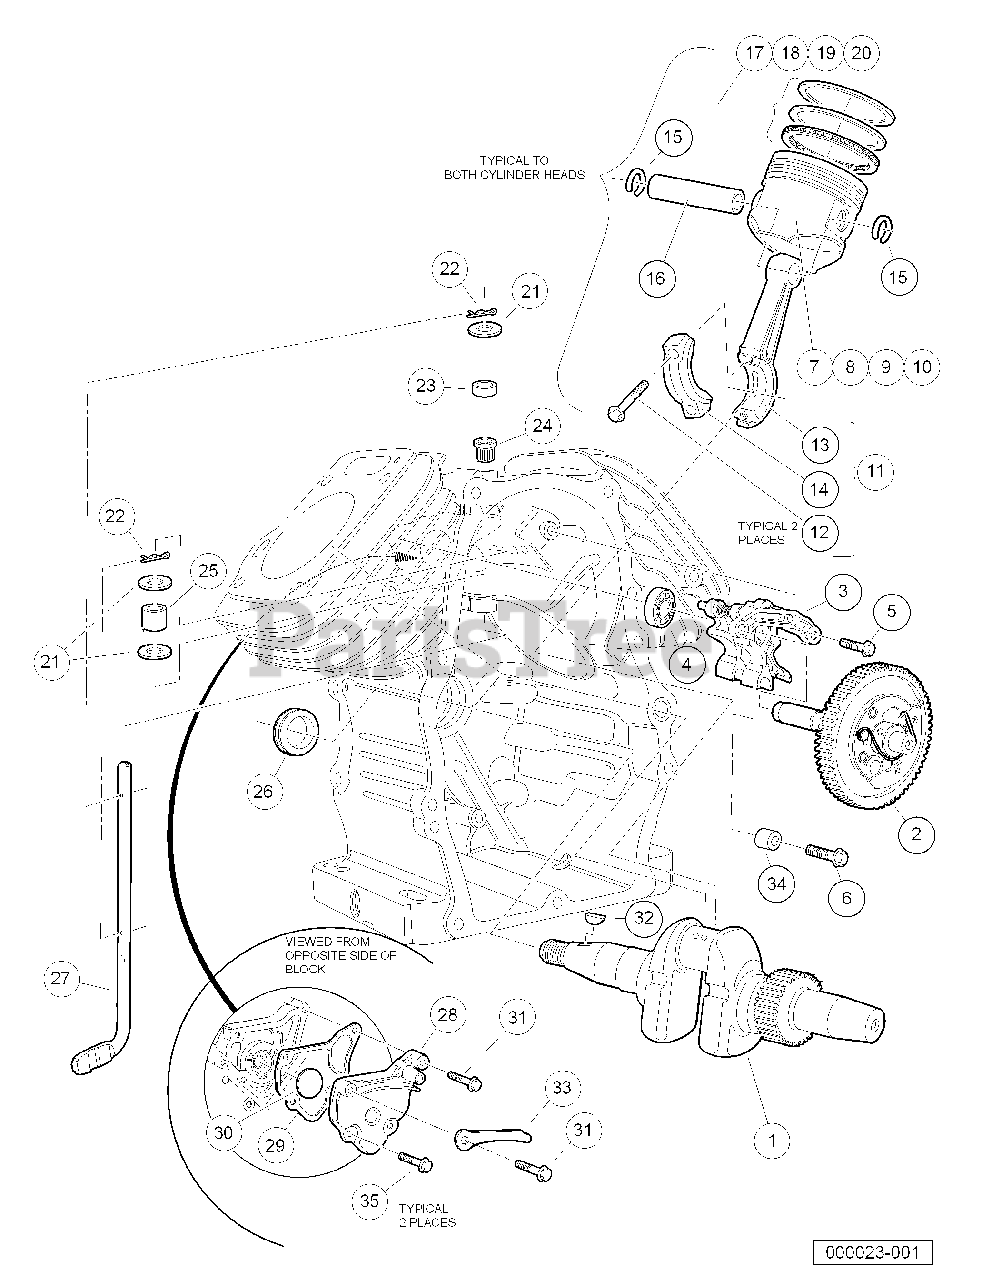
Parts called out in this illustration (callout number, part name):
1	Crankshaft
2	Camshaft Assembly
3	Lifter Assembly, Valve
4	Bearing, Radial Ball, 6003
5	Bolt, Flange Head, M5 X 1 X 16
6	Bolt, Flange Head, M6 X 1 X 25
7	Piston, Std
8	Piston, Over-Sized 0.25
9	Piston, Over-Sized 0.50
10	Piston, 0.75
11	Rod Assy., Connecting
12	Bolt, Connecting Rod, 6 X 37
13	Connecting Rod
14	Cap, Connecting Rod
15	Clip, Piston Pin, 18mm
16	Pin, Piston
17	Ring Set, Piston, Std
18	Ring Set, Piston, OS 0.25
19	Ring Set, Piston, OS 0.50
20	Ring Set, Piston, OS 0.75
21	Washer, Plain, M8
22	Pin, Lock, 8 Mm
23	Bearing, Needle, 8 X 12.7 X 11
24	Oil Seal, 8 X 14 X 5
25	Bearing, Needle, 8 X 12 X 10
26	Oil Seal, 38 X 58 X 9
27	Shaft, Governor Arm
28	Cover, Breather
29	Gasket, Breather Cover
30	Valve, Breather
31	Bolt, Flange Head, M6 X 1 X 32
32	Key, Special Woodruff, 25 X 18
33	Clamp, Wire
34	Pin A, Dowel
35	Bolt, Flange Head, 6 X 16
